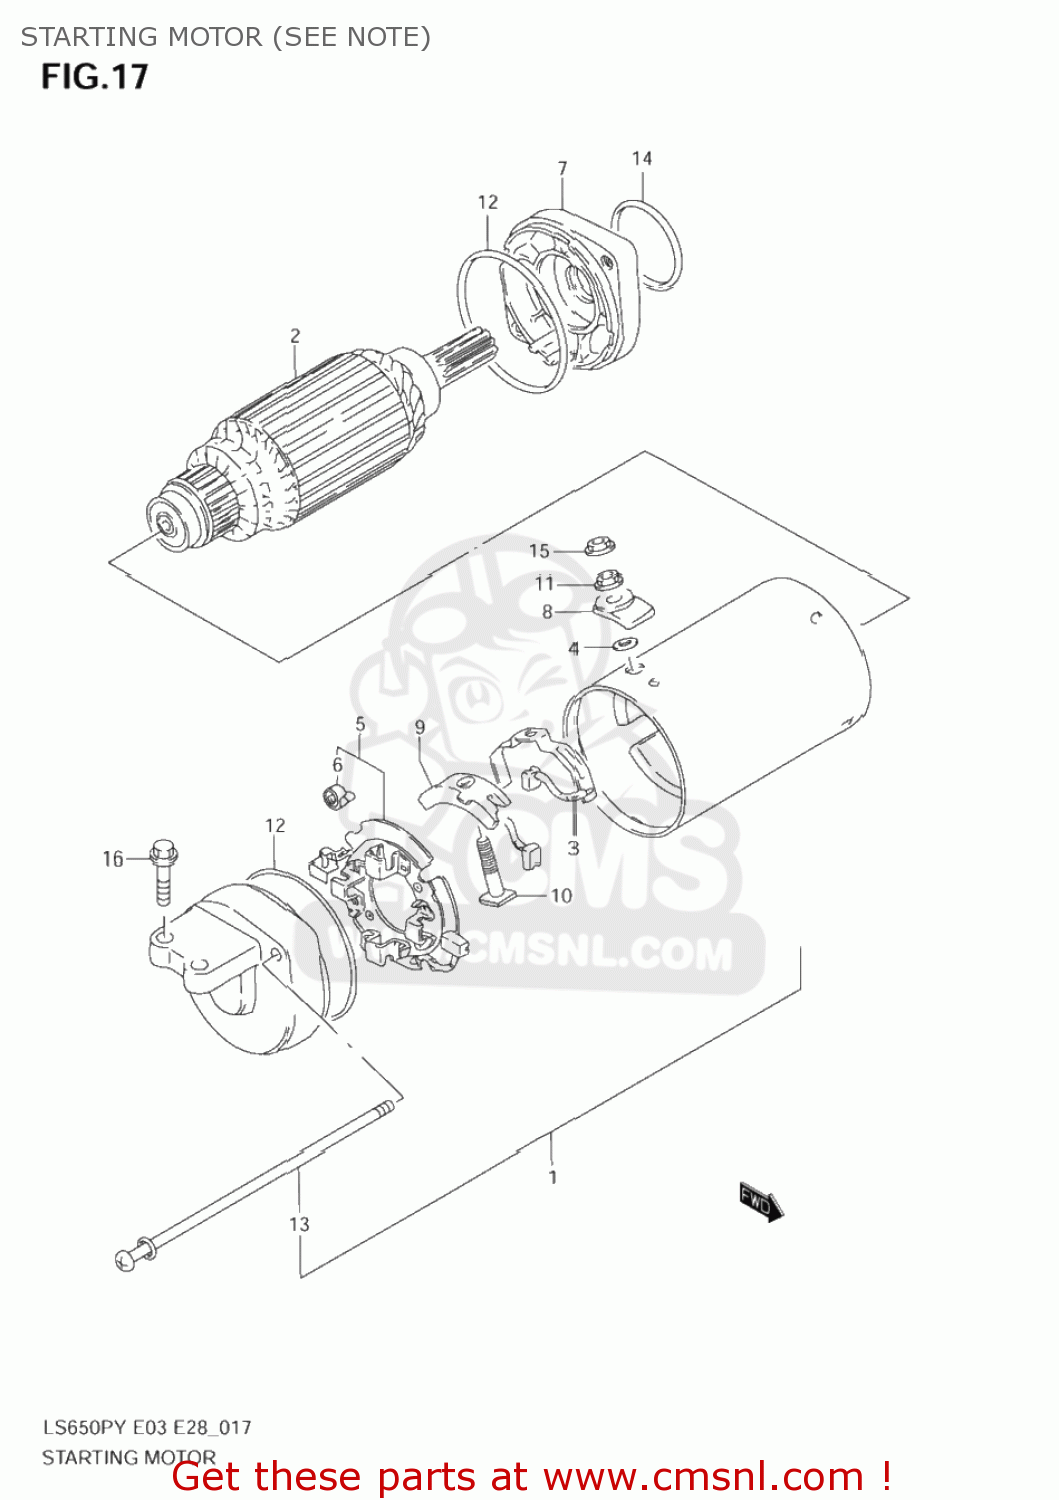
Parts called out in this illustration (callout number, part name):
1	MOTOR ASSY,STARTING
2	FRAME ASSY
3	O RING
4	HOLDER SET,BRUSH
5	SHIM SET,STARTING MOTOR
6	BRACKET SET
7	BUSHING
8	BUSHING
9	NUT
10	NUT
11	O RING
12	BOLT
13	O-RING (D:2.1 ID:34.7)
14	NUT
15	BOLT(6X20)
